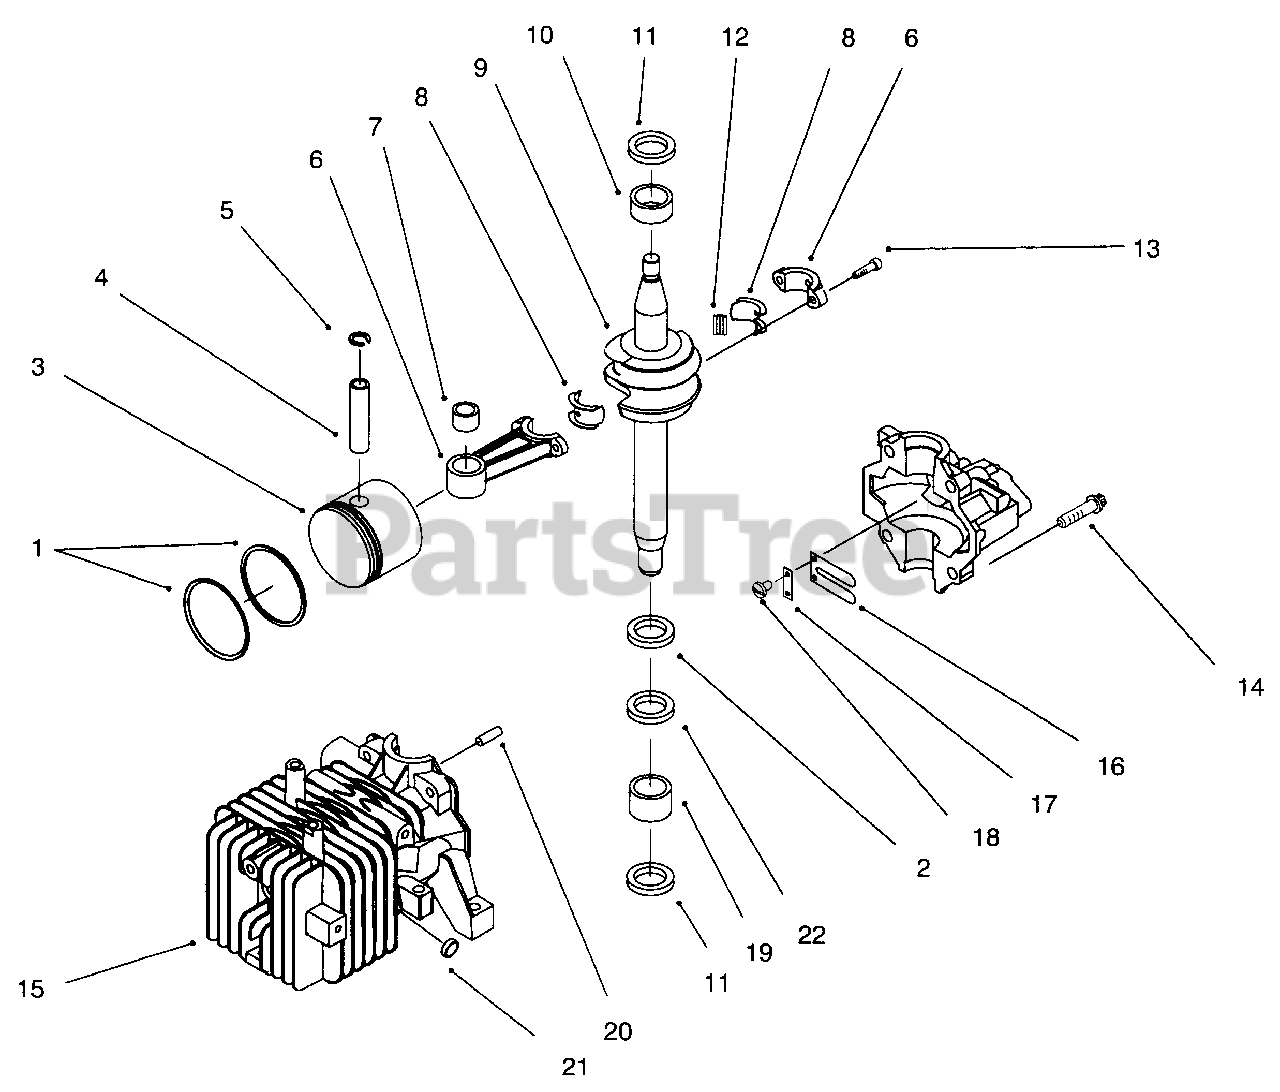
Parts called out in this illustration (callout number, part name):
1	Set-Ring
2	Bearing-Thrust
3	Piston & Connecting Rod (Incl. Ref. #1-2, 4-8, 12, & 13)
4	Pin-Wrist
5	Ring-Retaining
6	Connecting Rod Assembly (Incl. Ref. #6-8, 12, & 13)
8	Liner-Split (Set of 2)
9	Crankshaft
10	Bearing-Upper Main
11	Seal-Oil
12	Bearing-Needle
13	Screw-Hex. Hd.
14	Screw-Torx. Washer Hd.
16	Reed-Carburetor
17	Reed-Backup Plate
19	Bearing-Needle
21	Plug-Core
22	Washer-Thrust
